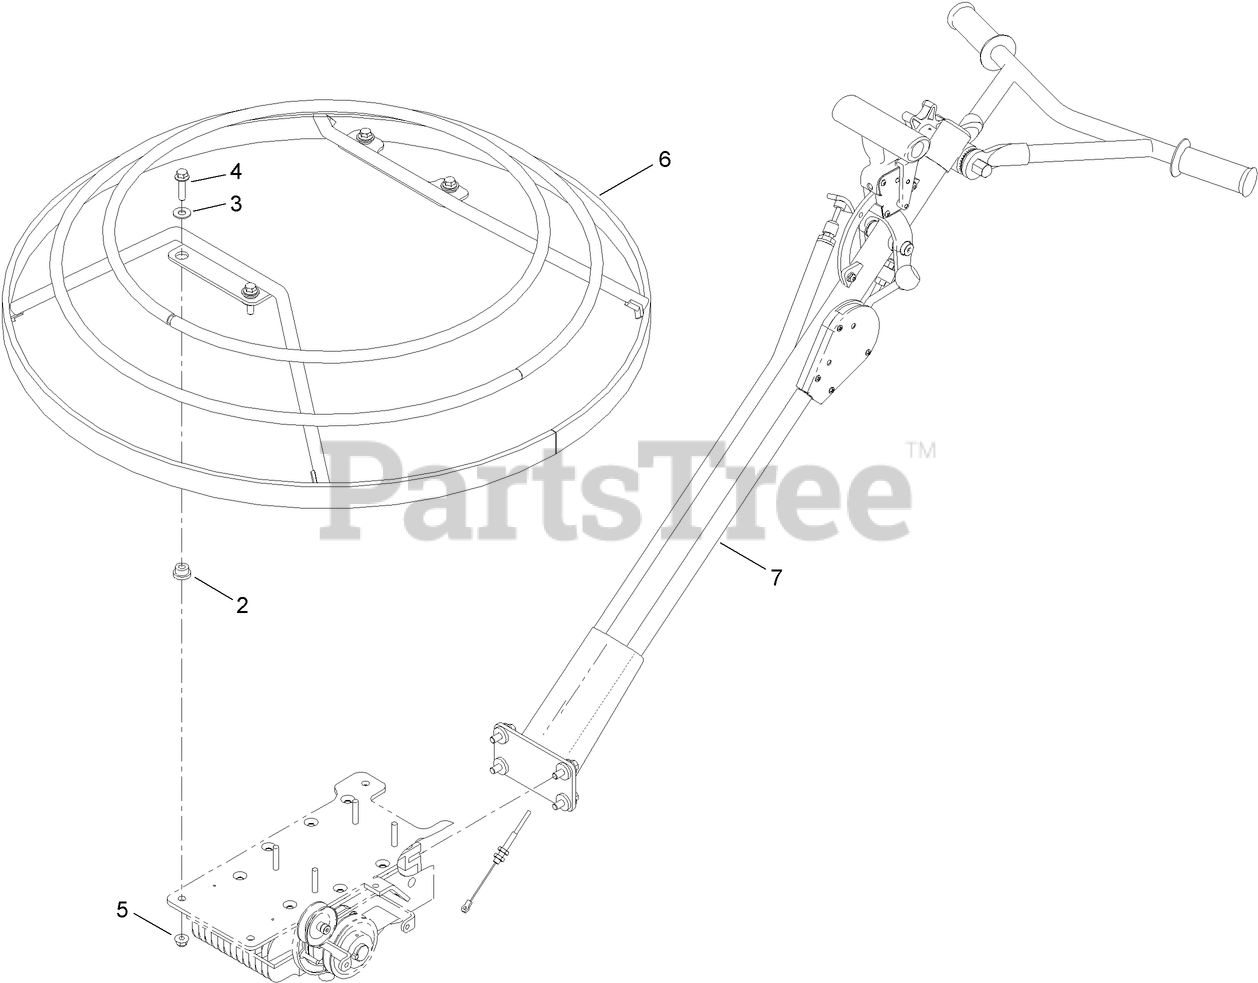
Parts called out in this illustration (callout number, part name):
2	MOUNT-SHOCK
3	WASHER-FLAT
4	SCREW-HHF
5	NUT-HF, NI
6	GUARD-STATIONARY
7	PRO-PITCH HANDLE ASM
